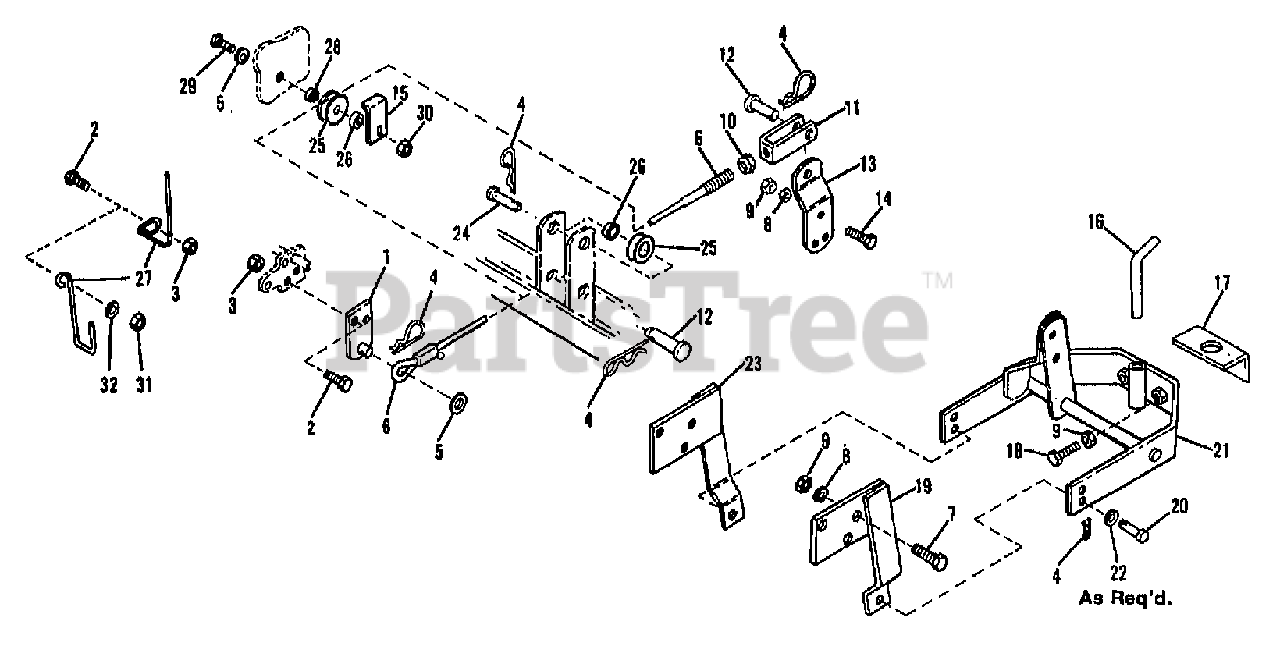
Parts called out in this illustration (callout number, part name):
1	ASSM-LIFT ARM
2	SCR-HFLK 3/8-16X1.00 ZP
3	NUT-HFLK 3/8-16 ZP
4	PIN-HITCH .125X2.56 ZP
5	WASHER-1.06X.531X.1 ZP
6	CABLE-LIFT
7	SCR-HH 1/2-13X1.25 G5 ZP
8	WASHER-LK .5
9	NUT-HEX JAM 1/2-13
10	NUT-HEX/JAM 3/8-16
11	YOKE-CABLE
12	PIN-CLEVIS .5X1.25
14	SCR-HH 1/2-13X1.5 G5 ZP
15	RETAINER-CABLE
16	PIN-HITCH .625 DIA
18	SCR-HH 1/2-13 X 2.00
19	ASSM-ARM HITCH LH
20	PIN-CLEVIS
22	WASHER-1.305X.649X.098 ZP
23	ASSM-ARM HITCH RH
24	PIN-CLEVIS
26	SPACER-.75X.53X.656
27	GUIDE-LIFT CABLE
27	GUIDE-CABLE
28	SPACER-.875X.531X.47
29	SCR-HH 1/2-13X2.5 G5 ZP
30	NUT-H/LK 1/2-13
31	NUT-H/LK 3/8-16
32	WASHER-.986X.437X.083 ZP
